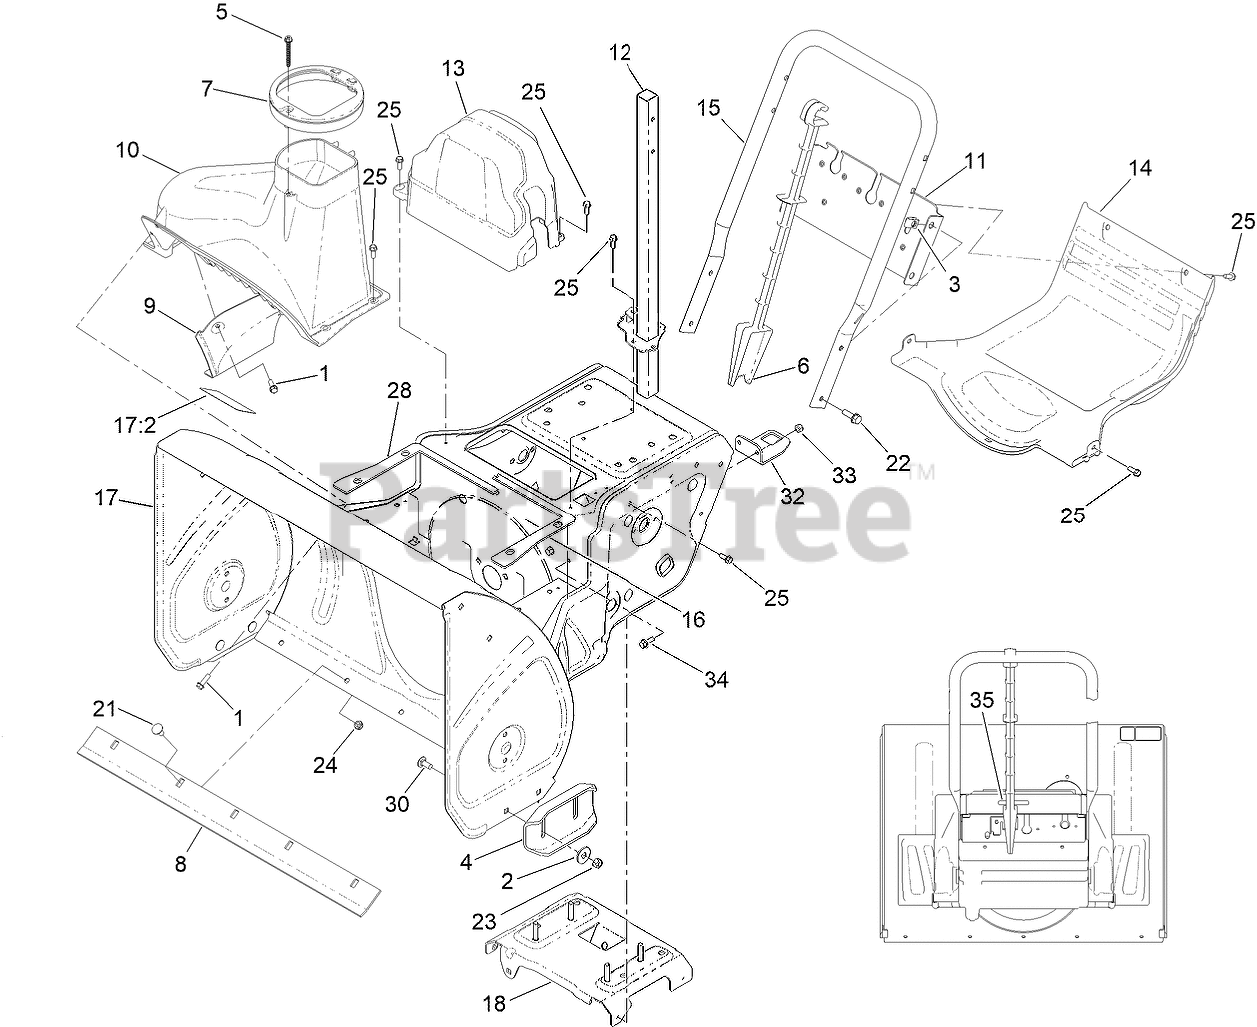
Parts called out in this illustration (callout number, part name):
1	SCREW-HWH
2	WASHER
3	NUT-U
5	SCREW-HWH, PLASTITE
6	STICK-CLEANOUT
7	GUIDE-CHUTE
8	SCRAPER-24 INCH
9	COVER-LINER
11	BRACE-FRAME
12	SUPPORT-CHUTE
13	COVER-BELT
14	COVER-LOWER
15	HANDLE-LOWER, CTS
16	SEAL-HOUSING, LH
17	FRAME (ASM COMPACT 2 STAGE 24IN W/DECAL)
17:2	DECAL-DANGER, AUGER
18	BRACE-FRAME
21	SCREW-CARR
22	SCREW-HHF
23	NUT-LOCK, NI
24	NUT-LOCK, NI
25	SCREW-HWH
28	SEAL-HOUSING, RH
30	SCREW-CARR
32	BRACKET-POST, CHUTE
33	SCREW-HHF
34	NUT-HEX
35	DECAL-WARNING
